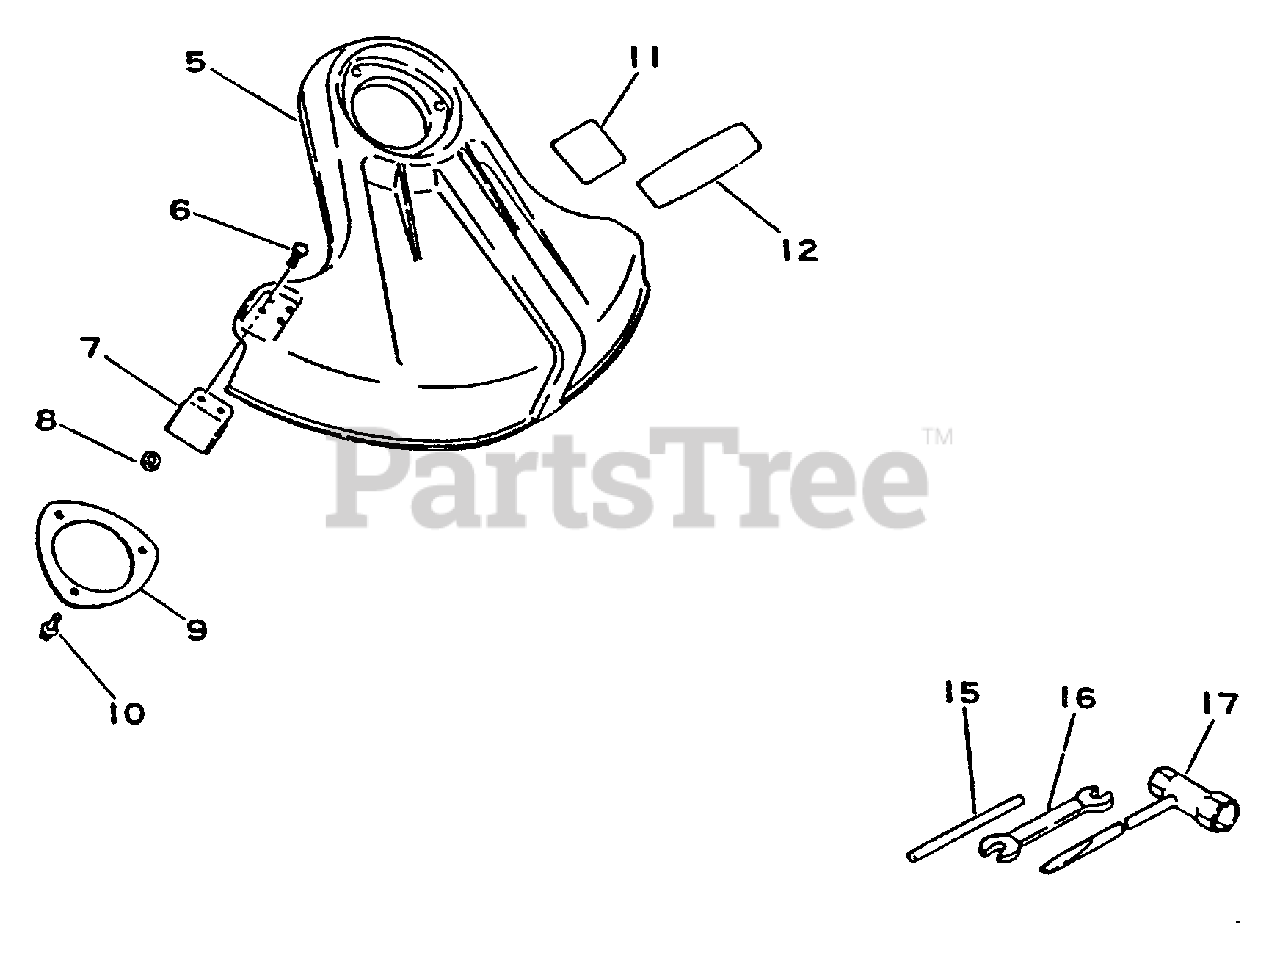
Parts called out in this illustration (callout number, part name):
5	Shield
6	Screw 5=16
7	Knife, Cord
9	Bracket, Shield
10	Screw 5=16
11	Label, Caution
12	Label, Echo
15	Locking Tool
16	Spanner 8=10
17	Wrench, W/S-Driver
